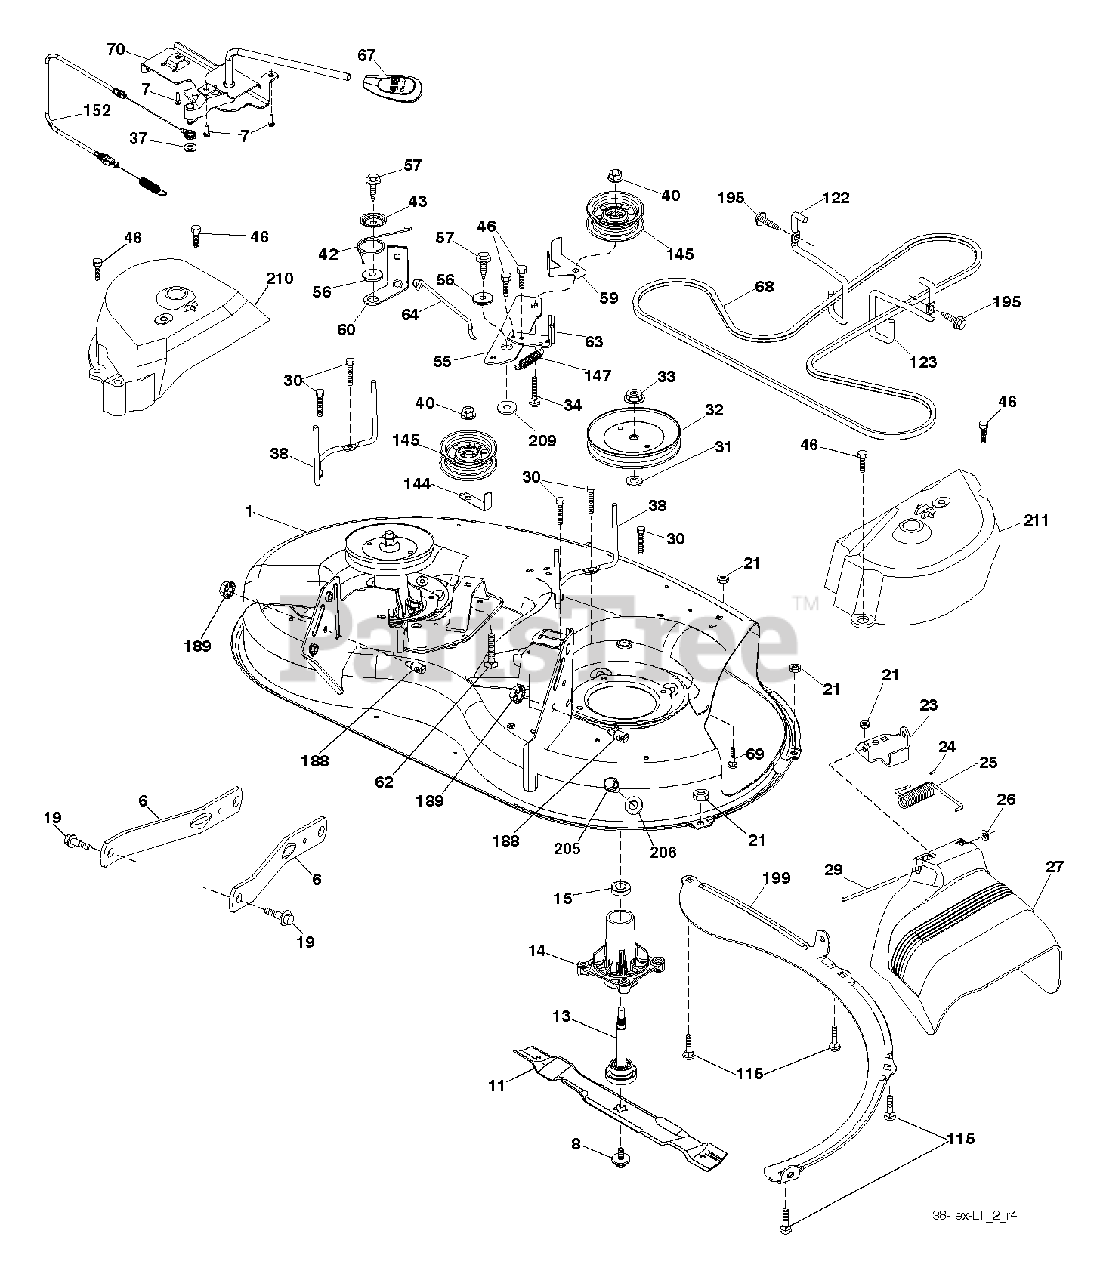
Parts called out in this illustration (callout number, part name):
6	ARM.SUSPENSION.MOWER.R
7	SCREW
8	BOLT.WASHER.ASM.7/16-2
11	BLADE 38" PREMIUM
13	SHAFT.ASM.MDRL.N/GREASE.38
14	HOUSING MANDREL
19	BOLT.SHOULDER
21	LOCKNUT
23	BRKT.DEFLECTOR.38"2005+
24	CAP-SLEEVE LT
25	SPRING.TORSION.DEFLECT
26	NUT PUSH M
29	ROD.HINGE
30	SCREW, WASHER HEAD
31	WASHER.SPACER.MANDREL
32	PULLEY.MANDREL.5.0.PD.38"
33	NUT.FLANGE.LOCK.TOP
34	BOLT.3/8-16X1.50
38	KEEPER BELT LH MANDREL
40	NUT LOCK FLG 3/8-16 UNC
42	SPRING.TORSION.BRAKE
43	SRPING.TORSION.RETAINE
46	SCREW.1/4-20X5/8
55	IDLER.ARM
56	SPACER.RETAINER
57	SCREW 3/8-16X1
59	GUARD, BELT
60	ARM BRAKE MOWER RH 38"
62	BOLT.3/8-16X1.50
63	ARM BRAKE MOWER RH
64	LINK BRAKE
67	HANDLE.CLUTCH.CABLE.LT
69	BOLT
70	CLUTCH.ASM.MANUAL.LT.TEX
115	BOLT
122	KEEPER BELT ENGINE LH
123	KEEPER BELT RH
144	KEEPER BELT
145	PULLEY.IDLER.48"PRIMARY
147	SPRING RETURN
152	CLUTCH CABLE
188	STUD.FASTNER.W/ANTI-ROTATE
189	NUT LOCK HEX FLANGE 5/16-18
195	SCREW, 3/8-16X3/4
199	BAFFLE VORTEX
205	SCREW
209	WASHER 12/32X2X10GA
